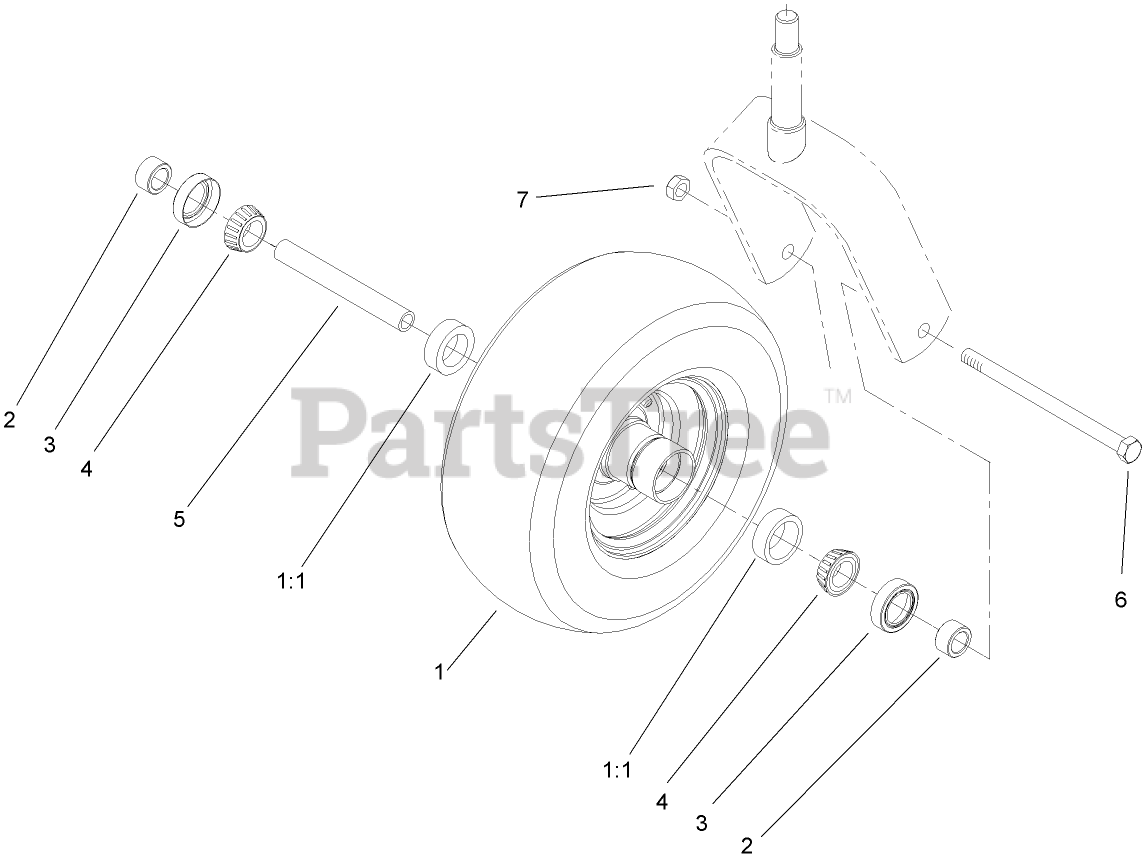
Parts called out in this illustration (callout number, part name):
1	WHEEL AND TIRE ASM (SEMI-PNEUMATIC)
1:1	BEARING-CUP
2	SPACER-BEARING
3	SEAL-BEARING
4	BEARING-CONE, TAPER
5	SPACER-CASTER, FRONT
6	SCREW-HH
7	NUT-LOCK, NI
